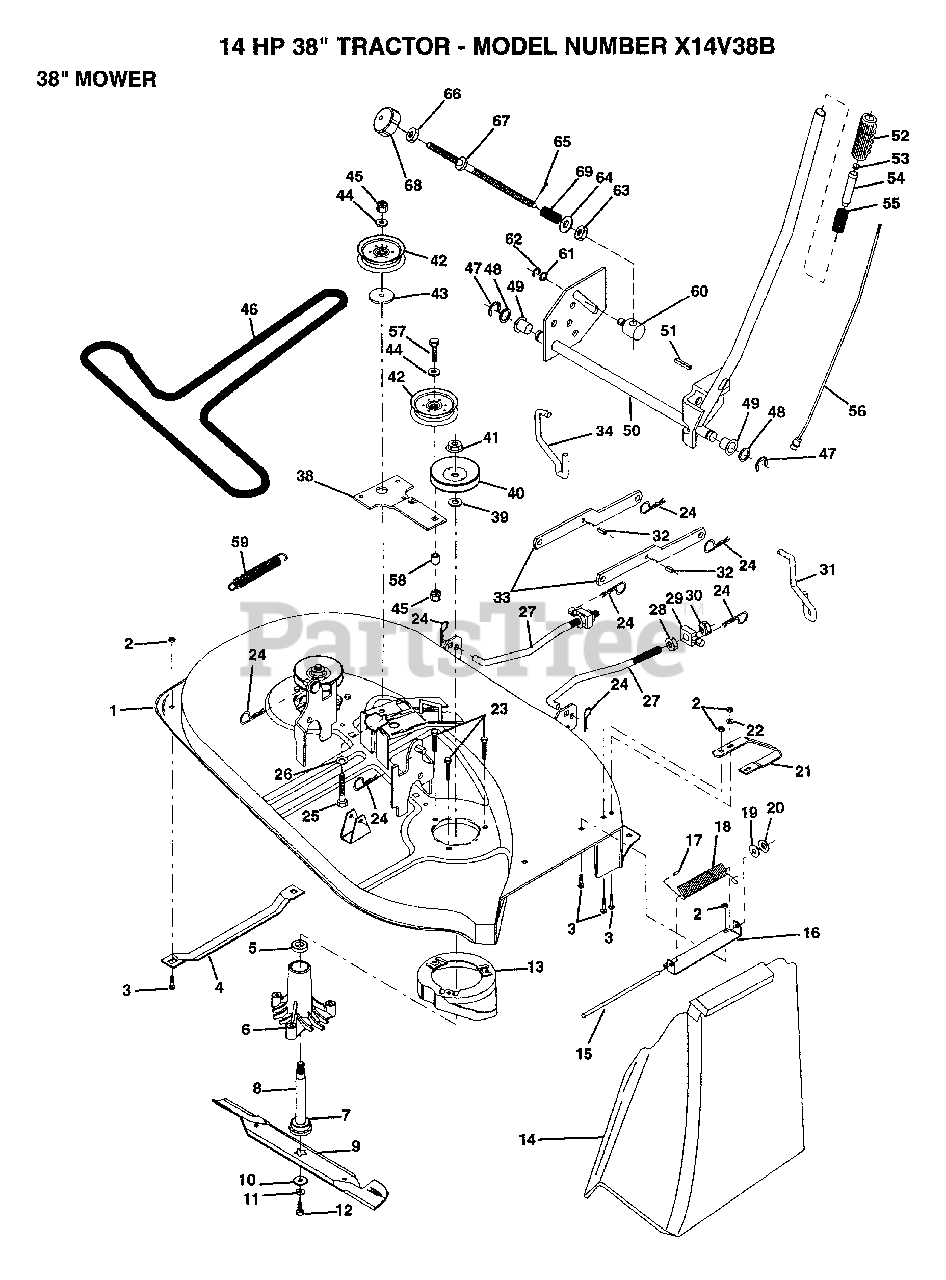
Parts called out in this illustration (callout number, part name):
3	BOLT
4	RUNNER-LH M
5	BEARING
6	HSG ASM MANDREL
7	BEARING.BALL
10	WASHER BLADE
12	BLADE BOLT
14	DEFLECTOR-SHLD T
15	ROD-HINGE T
17	NUT PUSH M
19	WASHER
20	CAP-SLEEVE LT
21	RUNNER RH
22	WASHER M
25	BOLT
26	WASHER GT
27	LINK.FRONT
28	NUT
29	TRUNION
30	NUT.LK.W/WSH.1/2.
31	LIFT LINK RH
32	"PIN,SPRING"
34	LINK LIFT LH
38	IDLER ARM ASSY
39	WASHER
42	FLAT IDLER PULLEY
43	SPACER RETAINER
44	WASHER
46	BELT-V.88.12.MW
48	WASHER
49	NYLON BEARING
51	PIN-GROOVE LT
52	GRIP
57	BOLT
59	SPRING.EXTENSION
60	TRUNION LT
61	WASHER
62	KLIP RING
63	NUT T
64	WASHER
66	NUT
69	SPRING T
